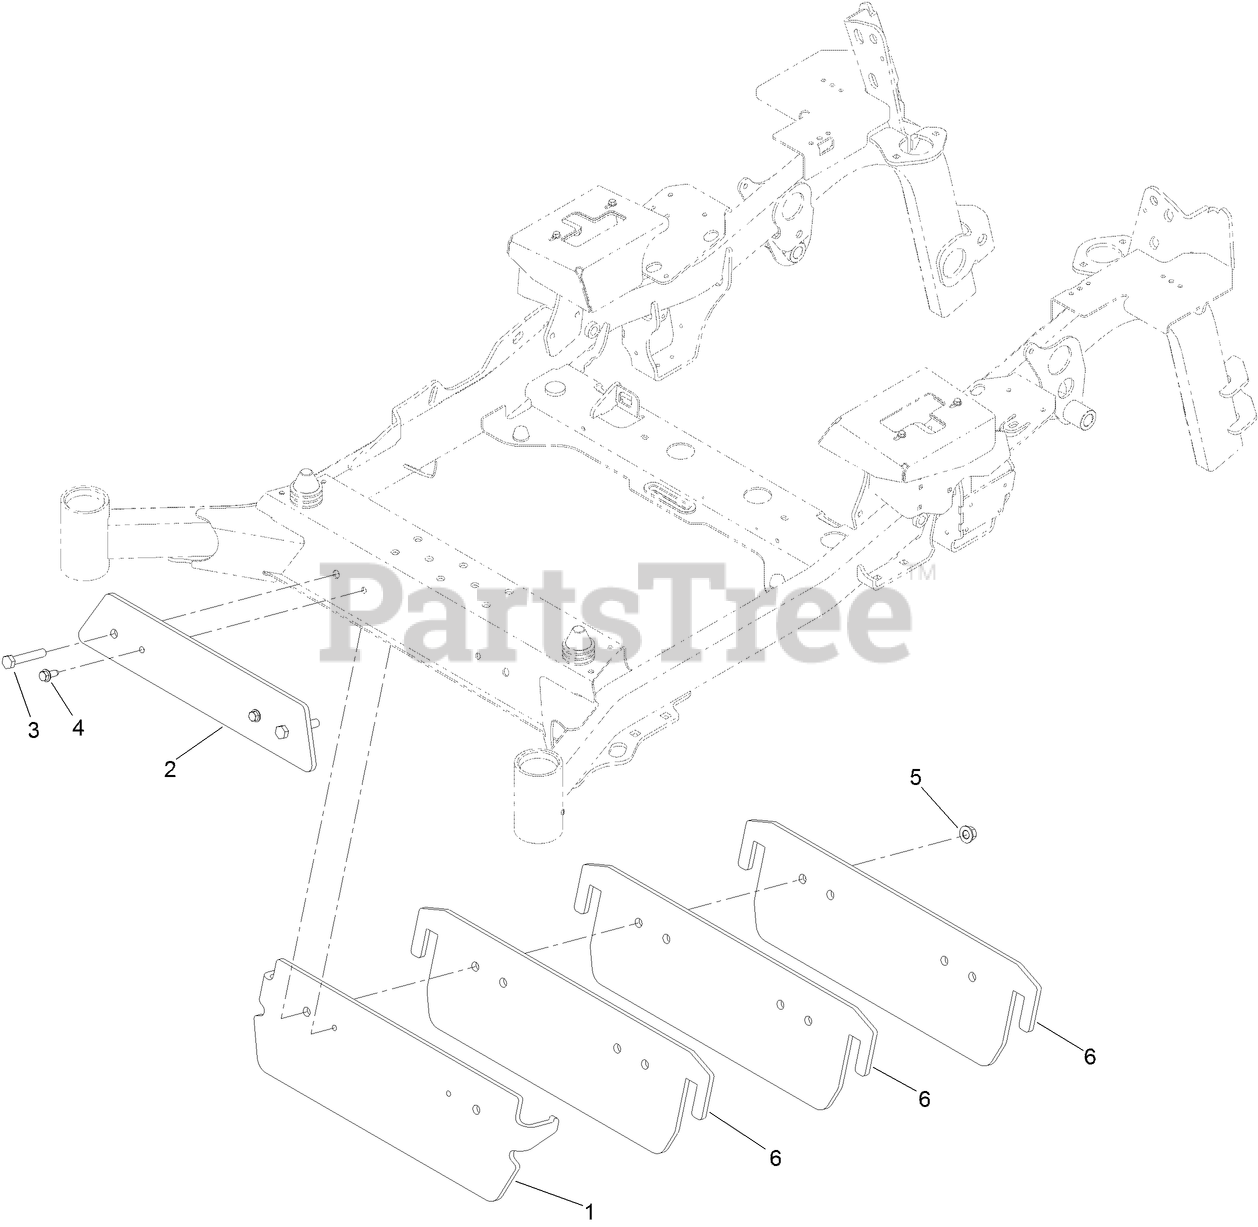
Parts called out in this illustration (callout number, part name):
1	BRACKET-WEIGHT
2	WEIGHT-OUTER
3	SCREW-HH, TAP
4	SCREW-FORMING, THREAD
5	NUT-LOCK
6	WEIGHT-INNER
